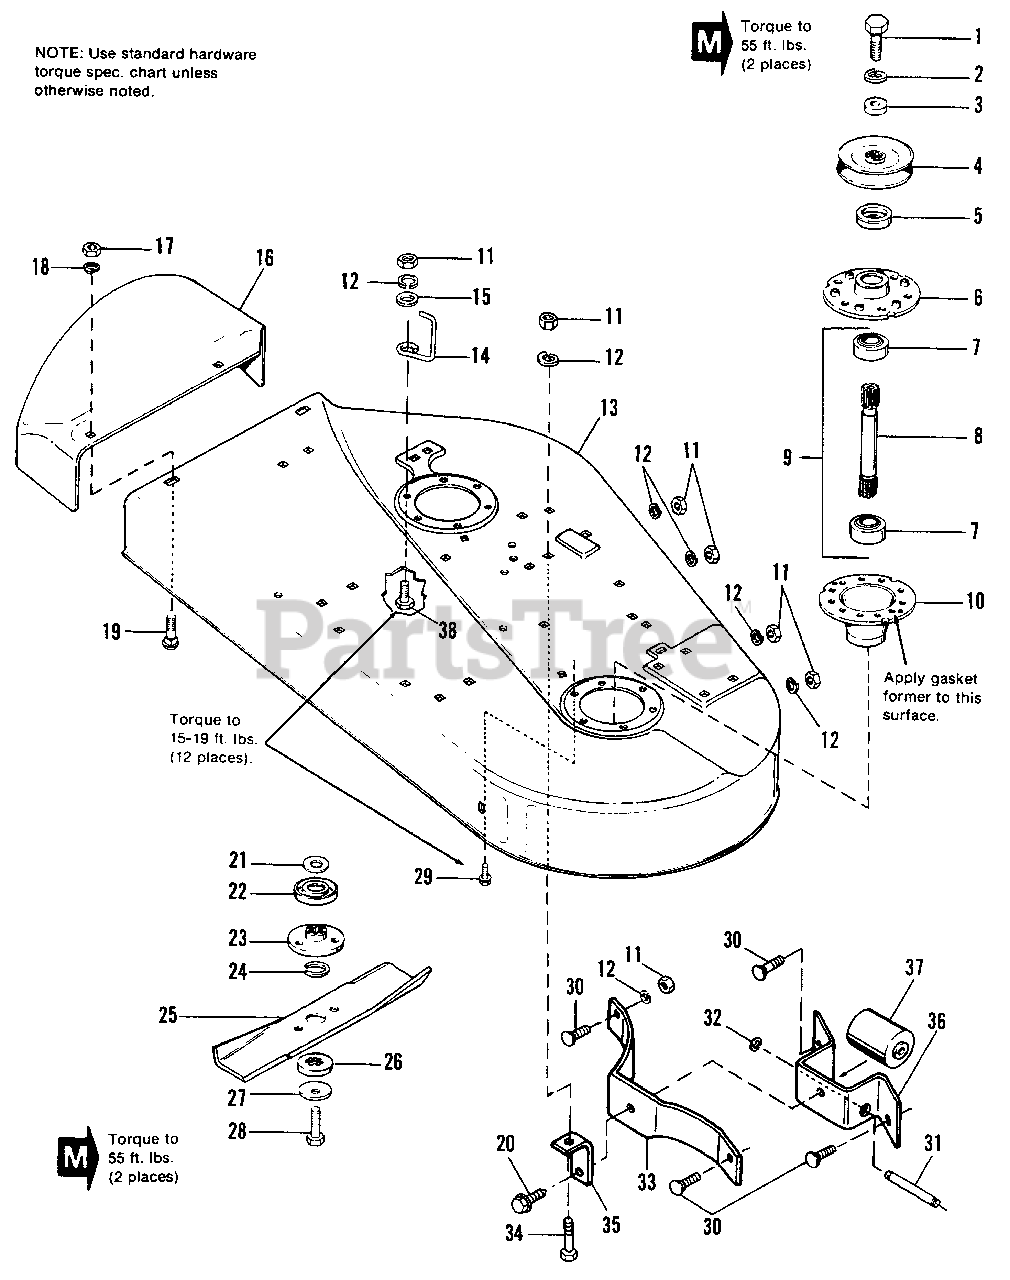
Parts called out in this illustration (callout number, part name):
1	CAPSCREW, Hex Hd., 7/16-14 x 2-3/4
2	LOCKWASHER, 7/16
3	WASHER, Special
4	PULLEY ASSY.
5	SHIELD, Bearing Upper, Arbor
6	HOUSING, Top
8	SHAFT, Arbor
9	SHAFT & BEARING ASSY.
10	HOUSING, Bottom
11	NUT, Hex, Full, 5/16-18
12	LOCKWASHER, 5/16
13	HOUSING, 36", with Decals
15	WASHER, 5/16
16	DEFLECTOR, Mower
17	NUT, Hex, Full, 3/8-16
18	LOCKWASHER, 3/8
19	BOLT, Carriage, 3/8-16 x 3/4
20	SCREW, Hex, Wash. Hd., Taptite, 5/16-18 x 1/2
21	WASHER, Shim
22	SHIELD. Grass
23	ADAPTOR, Blade
24	RING, Self-Locking
26	WASHER, Spline
27	WASHER, Cup
28	CAPSCREW, Hex Hd., 7/16-14 x 1
29	SCREW, Hex, Wash. Hd., Taptite, 5/16-18 x 3/4
30	BOLT, Carriage, 5/16-18 x 3/4
31	SHAFT, Roller, Center
32	E-RING
34	CAPSCREW, Hex Hd., 5/16-18 x 3/4
35	BRACKET, Mower
36	BRACKET, Center, Roller
38	SCREW, Hex Hd., Taptite, 5/16-18 x 1
